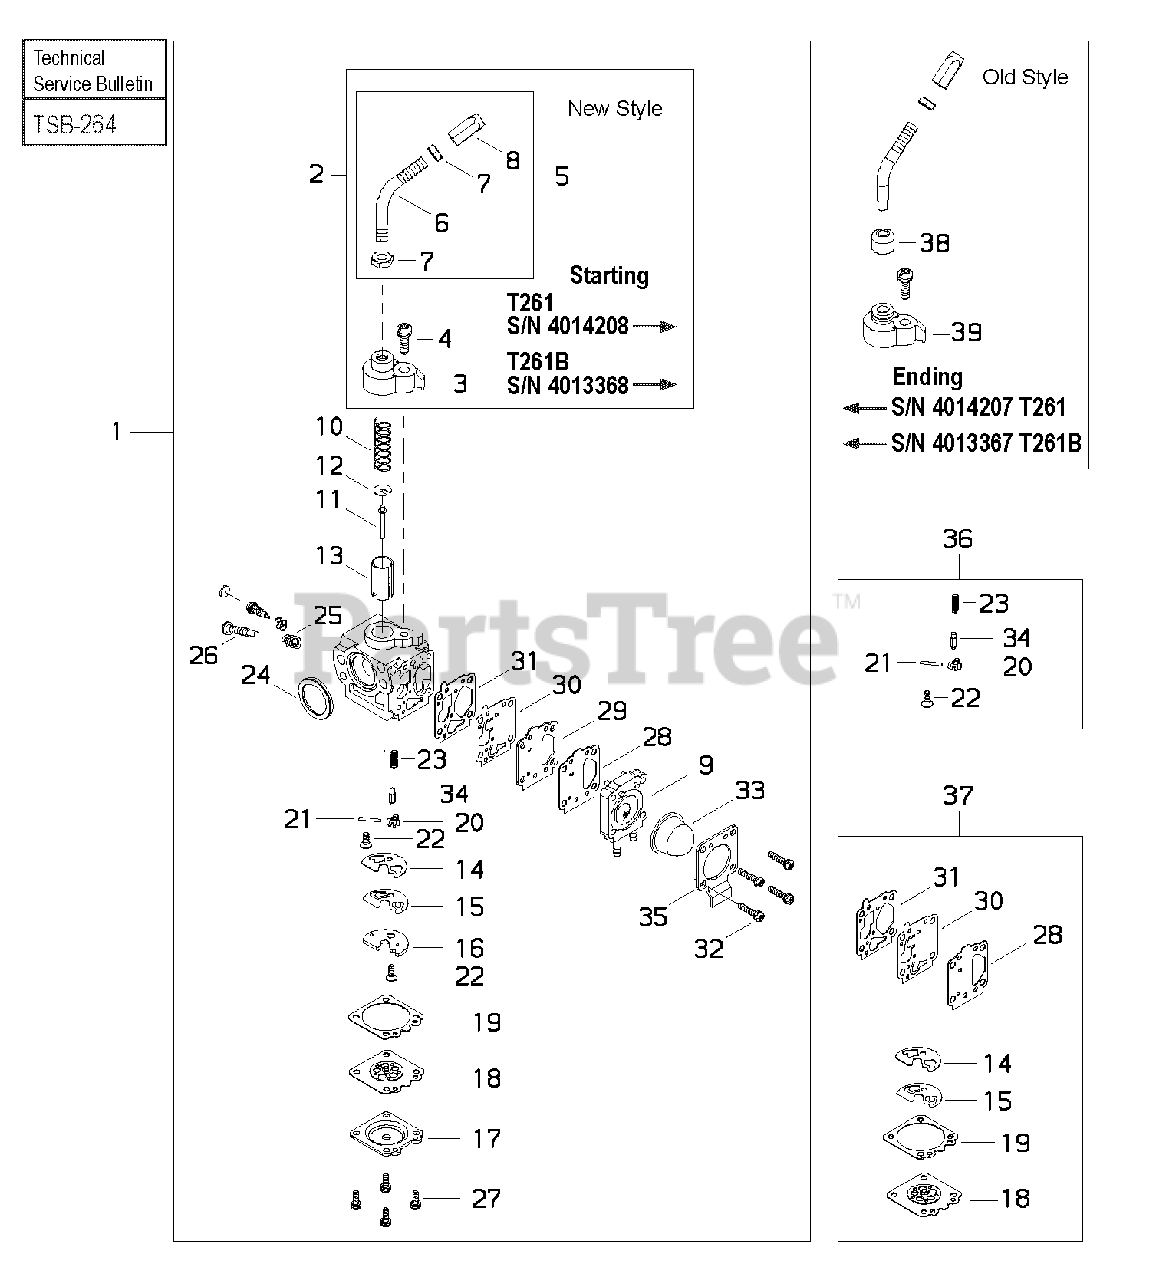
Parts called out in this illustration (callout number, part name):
1	CARBURETOR
2	ADJUSTER ASSY, CABLE
3	CAP, CARBURETOR
4	SCREW M5×15
5	ELBOW ASSY
6	ELBOW
7	NUT, LOCK
8	ADJUSTER, CABLE
9	COVER ASSY, PUMP
10	SPRING, THROTTLE
11	NEEDLE, JET
12	WASHER, SPRING SUPPORT
13	VALVE, THROTTLE
14	GASKET
15	VALVE, CHECK
16	PLATE
17	COVER, DIAPHRAGM
18	DIAPHRAGM, METERING
19	GASKET, METERING DIAPHRAGM
20	LEVER, METERING
21	PIN, METERING LEVER
22	SCREW M3×8
23	SPRING
24	RING, PACKING
25	SPRING
26	SCREW, IDLE ADJUST
27	SCREW M3×8
28	GASKET, FUEL PUMP
29	PLATE, PUMP
30	DIAPHRAGM, FUEL PUMP
31	GASKET, PUMP
32	SCREW M3×14
33	BULB, PURGE
34	VALVE, INLET NEEDLE
35	COVER, PUMP
36	VALVE KIT, INLET NEEDLE
37	GASKET / DIAPHRAGM KIT
38	CAP, DUST
39	CAP, CARBURETOR
